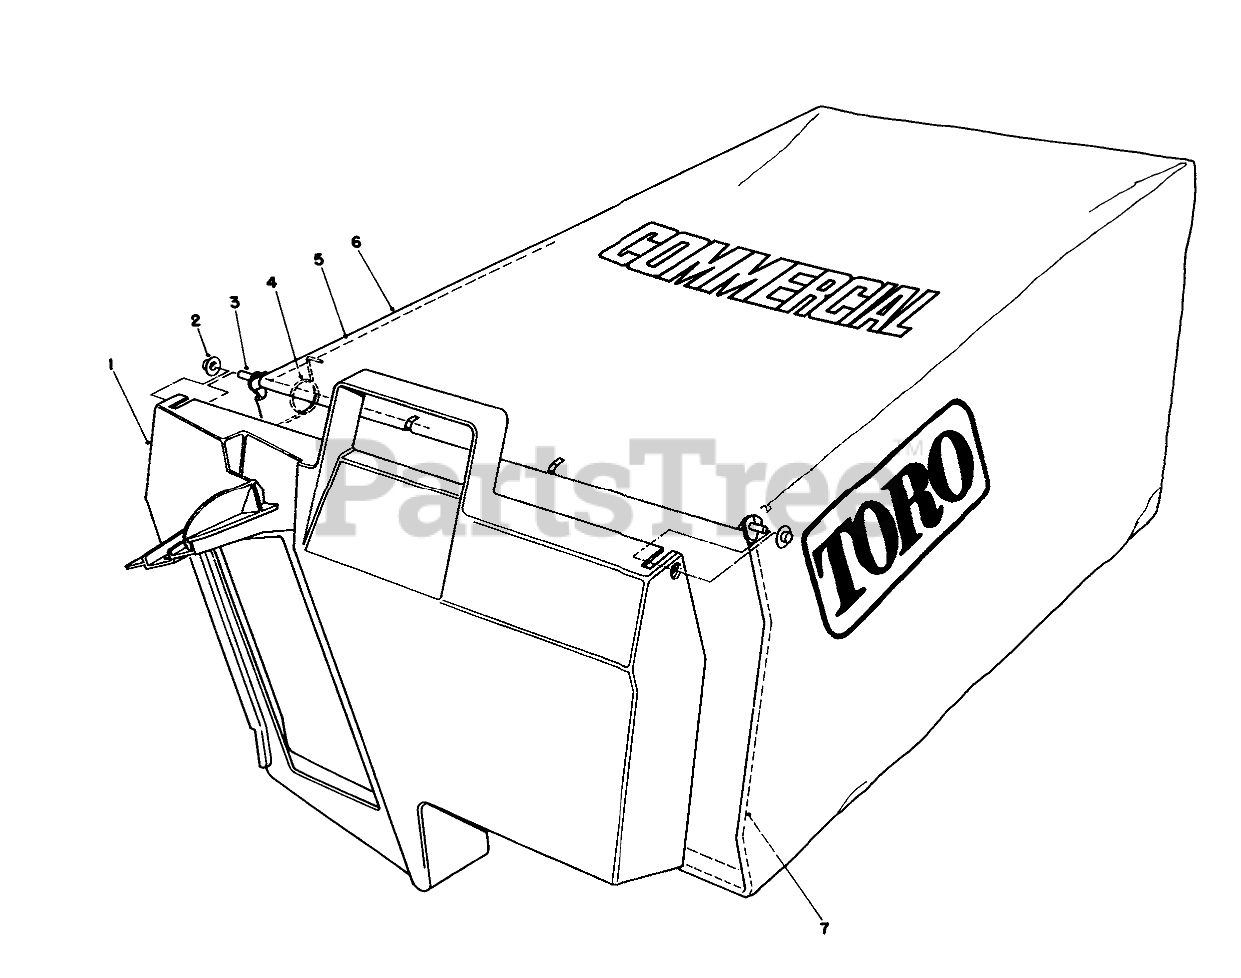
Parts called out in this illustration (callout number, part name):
1	DOOR-BAG, GRASS
2	NUT-PUSH
3	HINGE-DOOR, BAG
4	SPRING
5	FRAME-BAG, UPPER
6	Bag
7	FRAME-BAG
